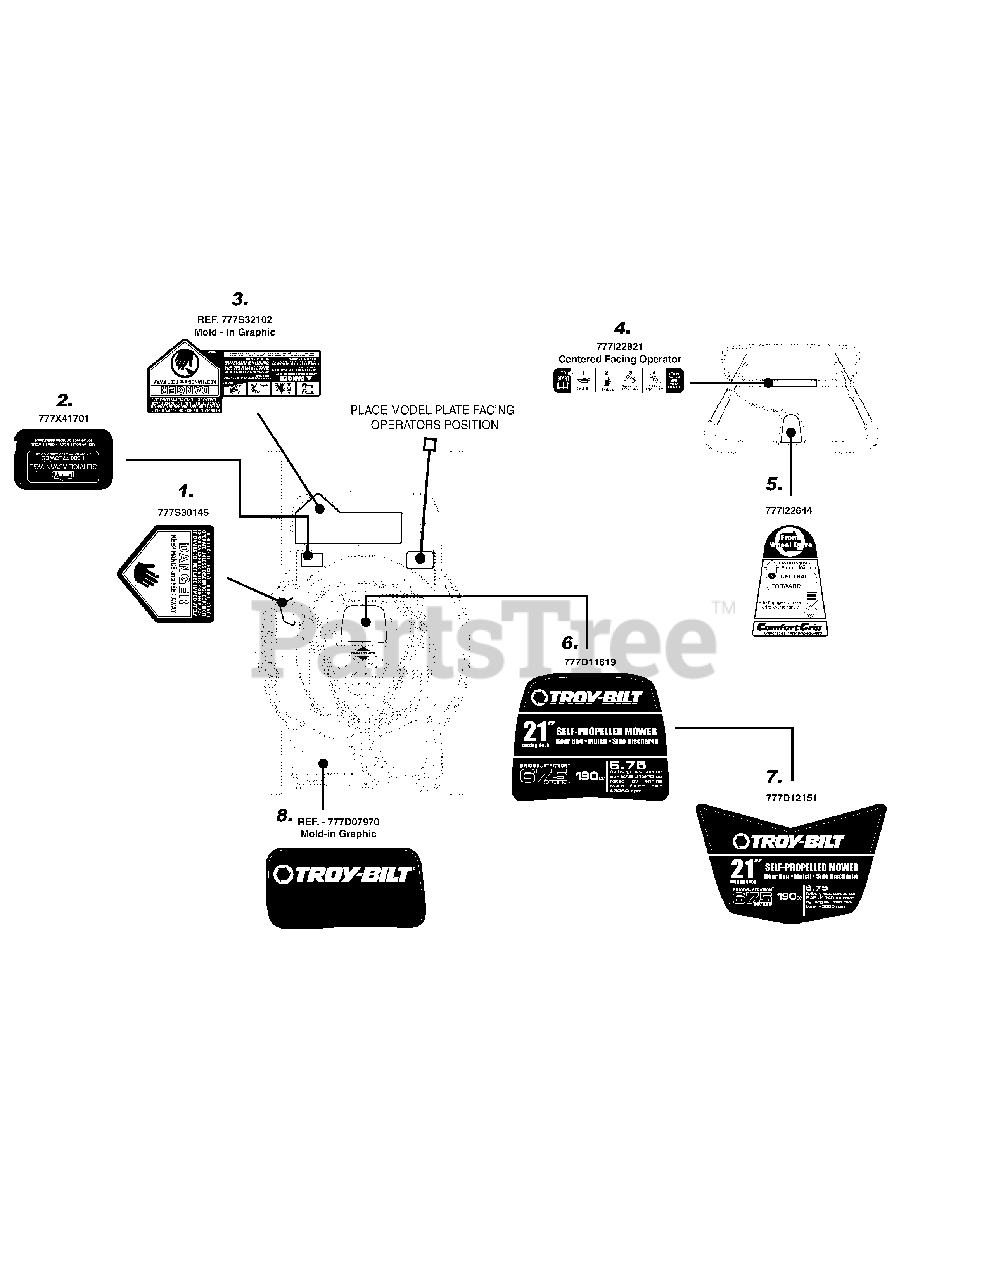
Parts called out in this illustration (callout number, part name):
1	LABEL
2	LBL:LOWES SERVICE ADVANTAGE
3	LABEL
4	LABEL-MOWER HANDLE B&S
5	LBL:MWR:HNDL:COMF/GRIP:FRNT:TB
6	LABEL-MOWER SHROUD TROY 675
7	LABEL-MOWER SHROUD TROY
8	LABEL - TROYBILT
